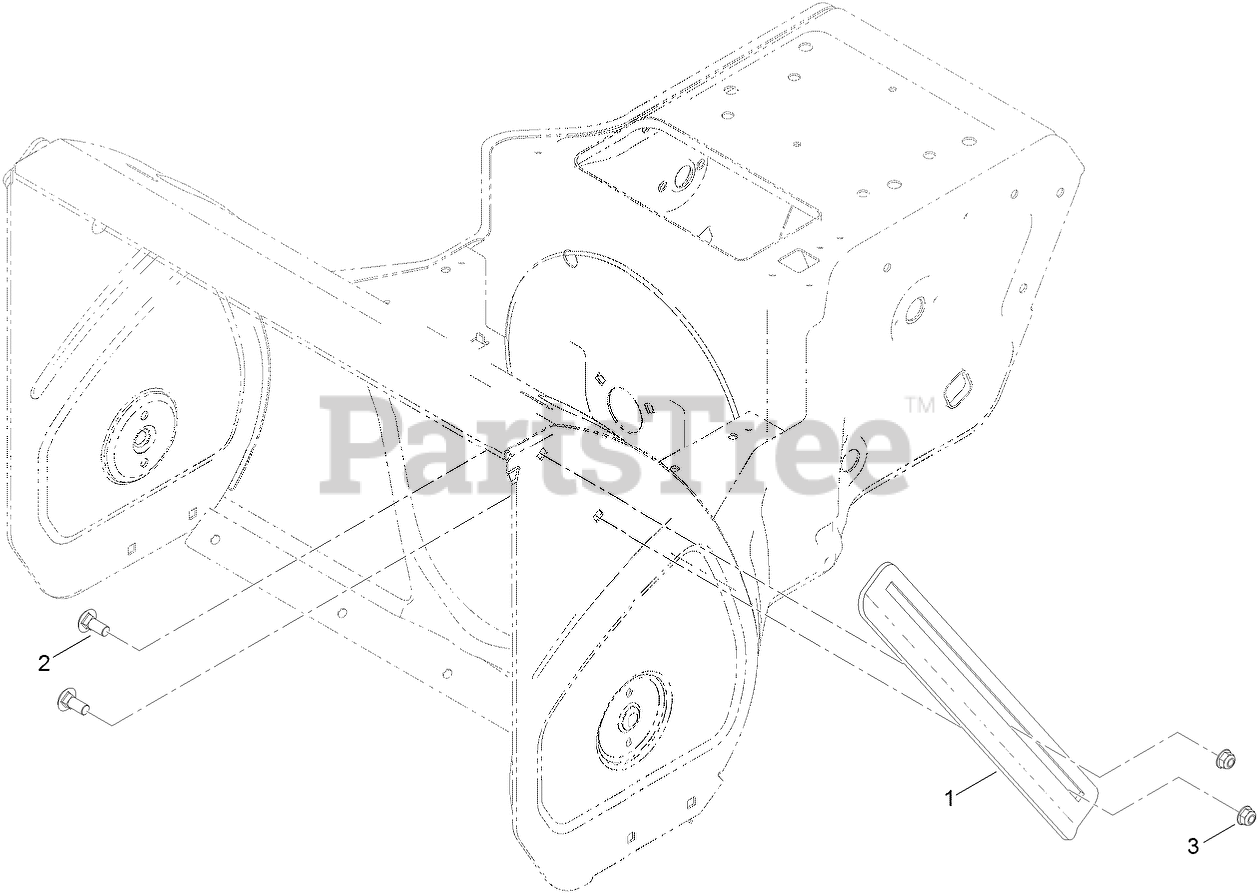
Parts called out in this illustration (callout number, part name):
1	BREAKER-DRIFT, SIDE
2	BOLT-CARR
3	NUT-HF, NI
